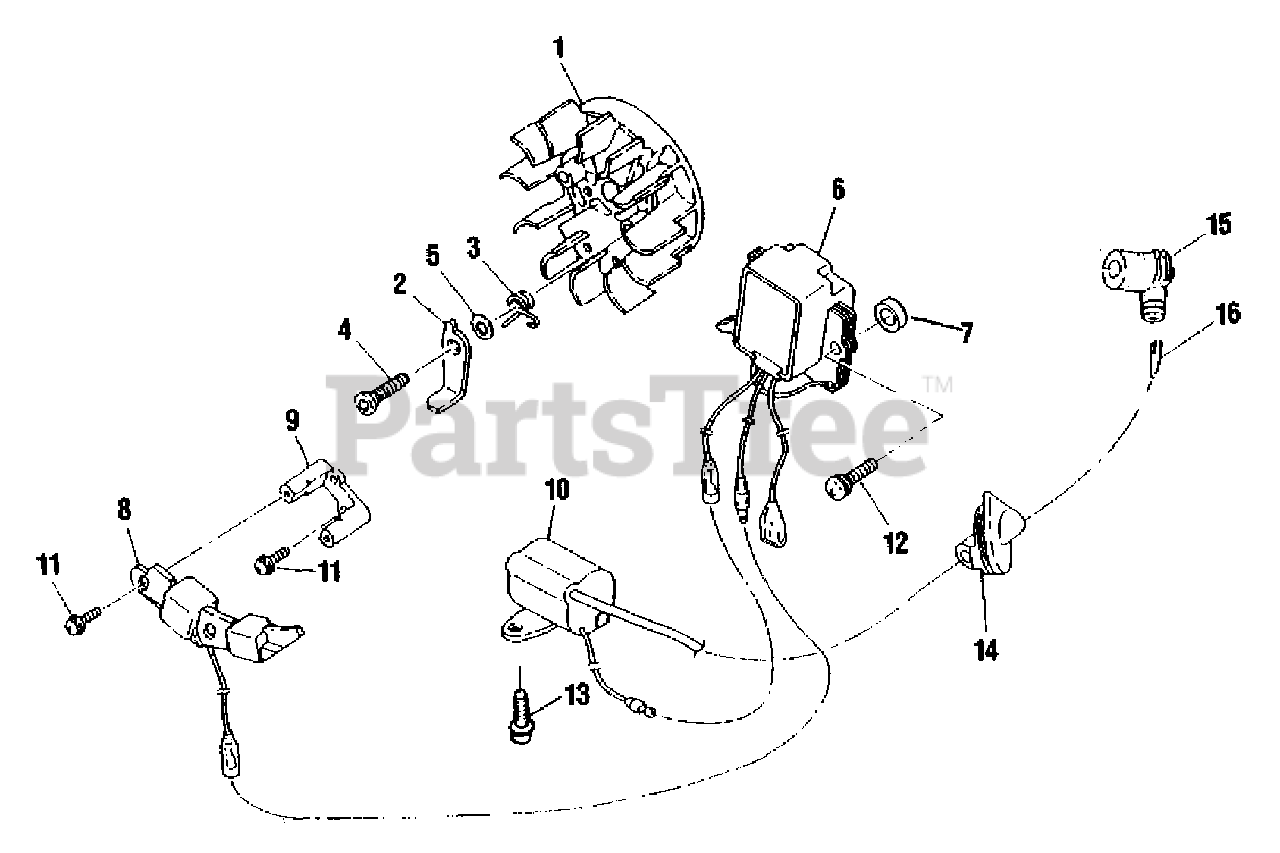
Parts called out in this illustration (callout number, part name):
1	ROTOR
2	RATCHET
3	RATCHET SPRING
4	BOLT M6
5	WASHER 6 MM
6	EXCITER, COIL
7	INSULATOR
8	PULSER COIL
9	PULSER BRACKET
10	COIL, IGNITION
11	SCREW
12	BOLT M5×20
15	CAP, SPARK PLUG
16	TERMINAL, SPARK PLUG
